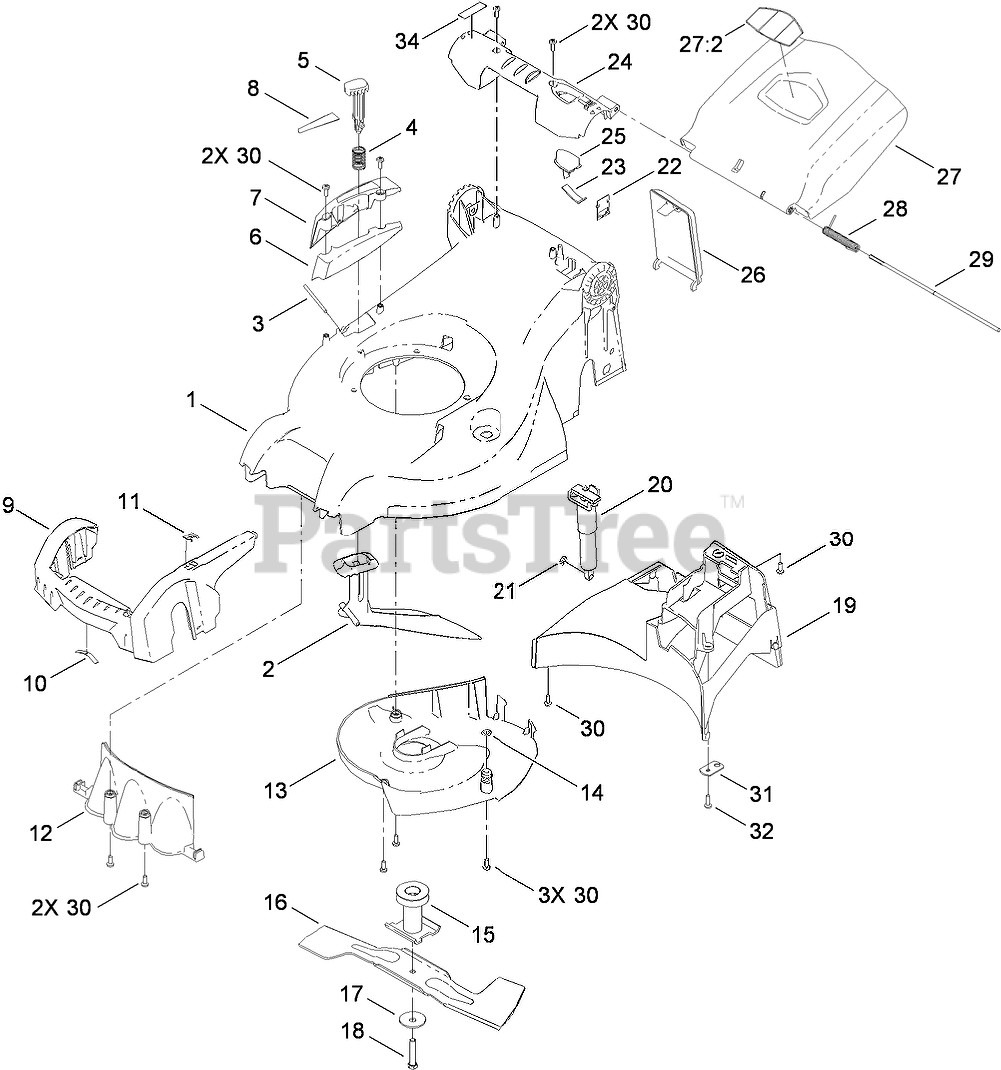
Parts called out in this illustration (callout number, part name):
1	DECK ASM
2	DOOR-ROD
3	PIN-DOOR, ROD
4	SPRING-DOOR, ROD
5	BUTTON-ROD
6	COVER-ROD, LEFT
7	COVER-ROD, RIGHT
9	BUMPER-FRONT
10	SPRING-LEAF, FRONT
11	LENSE-HOC
12	BAFFLE-FRONT
13	COVER-DECK
14	O-RING
15	BLADE DRIVER ASM
16	BLADE-ROTARY
17	WASHER-SPRING
18	SCREW-HH
19	BAFFLE-REAR
20	HOC CYLINDER ASM
21	CLIP-PUSH
22	PLATE-LOCKING
23	LEVER-BUTTON, HOC
24	HANDLE-DECK, REAR
25	BUTTON-HOC
26	COVER-BATTERY
27	REAR DOOR ASM
27:2	DECAL-WARNING
28	SPRING-DOOR, REAR
29	PIN-DOOR, REAR
30	SCREW-SPH, THREAD ROLLING
31	SUPPORT-CABLE, TRACTION
32	SCREW-RH
